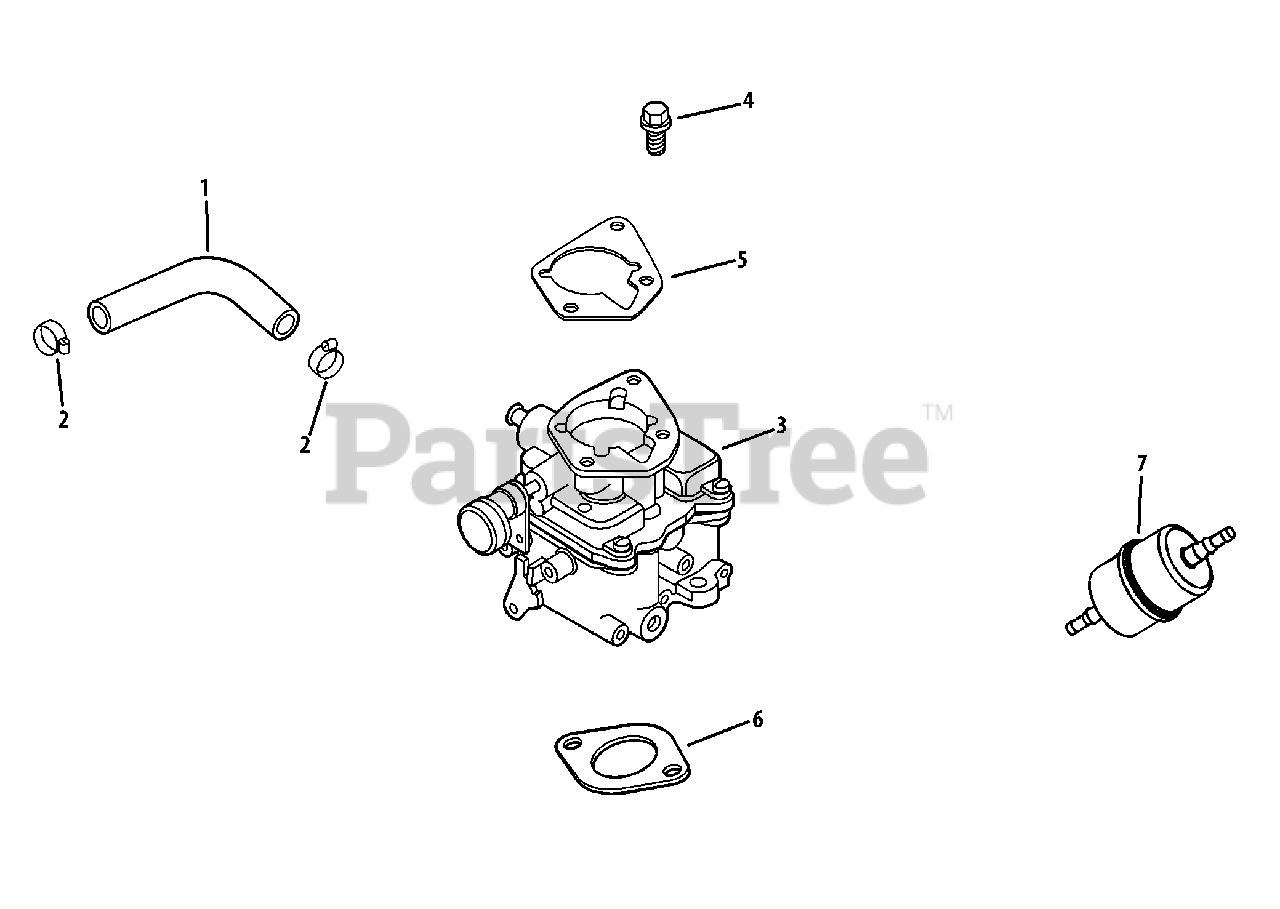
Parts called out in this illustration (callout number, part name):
1	Low Permeation Fuel Hose, 24"
2	Hose Clamp (KM)
3	Carburetor w/ Gaskets
4	Flange Screw, M6 x 1.0 x 25
5	Air Cleaner Base Gasket
6	Carburetor Gasket
7	Fuel Filter
